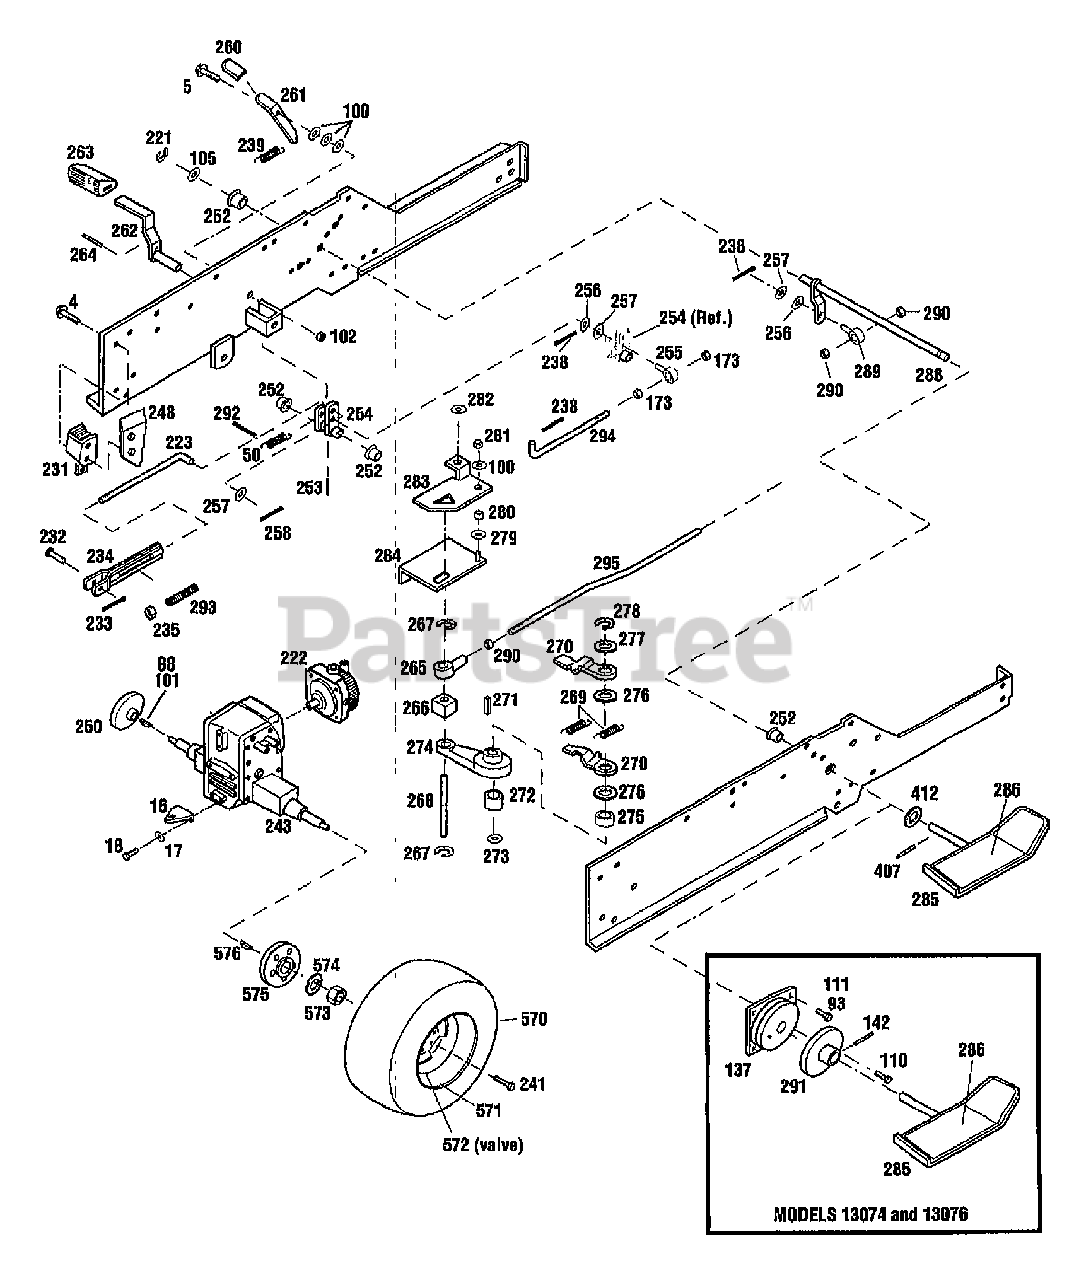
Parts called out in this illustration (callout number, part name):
5	SCR-HFLK 3/8-16X1.00 ZP
16	HITCH-DRAWBAR
17	WASHER-LK .5
18	SCR-HH 1/2-13X1.25 G5 ZP
68	KEY-WOODRUFF .188X.75
93	NUT W/LKWASHER 10-24 ZP
100	WASHER-FLAT 3/8 SAE
101	KEY-WOODRUFF .25X.75
102	NUT-LOCK 3/8-16
105	WASHER-1.115X.637X.06
111	SCR-SEMS MACH
137	CLUTCH
142	PIN-ROLL
173	NUT-HEX 5/16-18 ZP
221	RING-RETAIN .625 ID
222	PUMP-HYDRO
223	ROD-BRAKE
231	ASSY BRAKE-CYLINDER
232	PIN-CLEVIS .25X.62
233	PIN-COTTER
234	SPRING-YOKE ASSM
235	NUT-SPECIAL
238	PIN-COTTER .09X.75 ZP
239	SPRING
241	BOLT-HUB
243	ASSM-TRANSAXLE
248	BRKT-TRANS SUPPORT
250	BRAKE-DISC
250	DISC-BRAKE
252	BEARING-FLANGE
253	PIN-DRIVE .187X1.0
255	SWIVEL
256	WASHER-.632X.39X.0329
257	WASHER-FLAT 5/16 SAE
258	PIN-COTTER .125 X .75 ZP
262	PEDAL-BRAKE
263	FOOT REST
264	PIN-ROLL .188X.75
265	ROD-END
267	RING-RET.EXT .437 ID
268	PIN-CONTROL
269	SPRING
271	KEY-WOODRUFF 1/8 X 5/8
272	WASHER-1.06X.531X.1 ZP
273	NUT-H/LK 1/2-13
274	ARM-SPEED CONTROL
275	BEARING
276	WASHER-THRUST
277	WASHER
278	RING-RET
279	WASHER-1.75X.39X.059
280	SPACER-.625X.4X.2
281	NUT-HEX/JAM 3/8-16 ZP
281	NUT-H/LK 3/8-16
282	WASHER-.75X.312X.065 ZP
283	PLATE-NEUTRAL
284	PLATE-NEUTRAL
285	ASSM-PEDAL HYDRO
286	PAD-FOOT PEDAL
288	SHAFT-SPEED CONTROL
289	SWIVEL
290	NUT-HEX/JAM 7/16-20
291	ASSM-CONTROL DISC
292	PIN-COTTER .120X1.00 ZP
293	SPRING-COMPRESSION
294	ROD-BRAKE CONTROL
295	ROD-SPEED CONTROL
571	RIM-WHEEL REAR
572	STEM-VALVE
573	NUT-H/LK 3/4-10
574	SPACER-1.812X.765X.179
575	HUB-WHEEL
576	KEY-WOODRUFF .312X1.12
